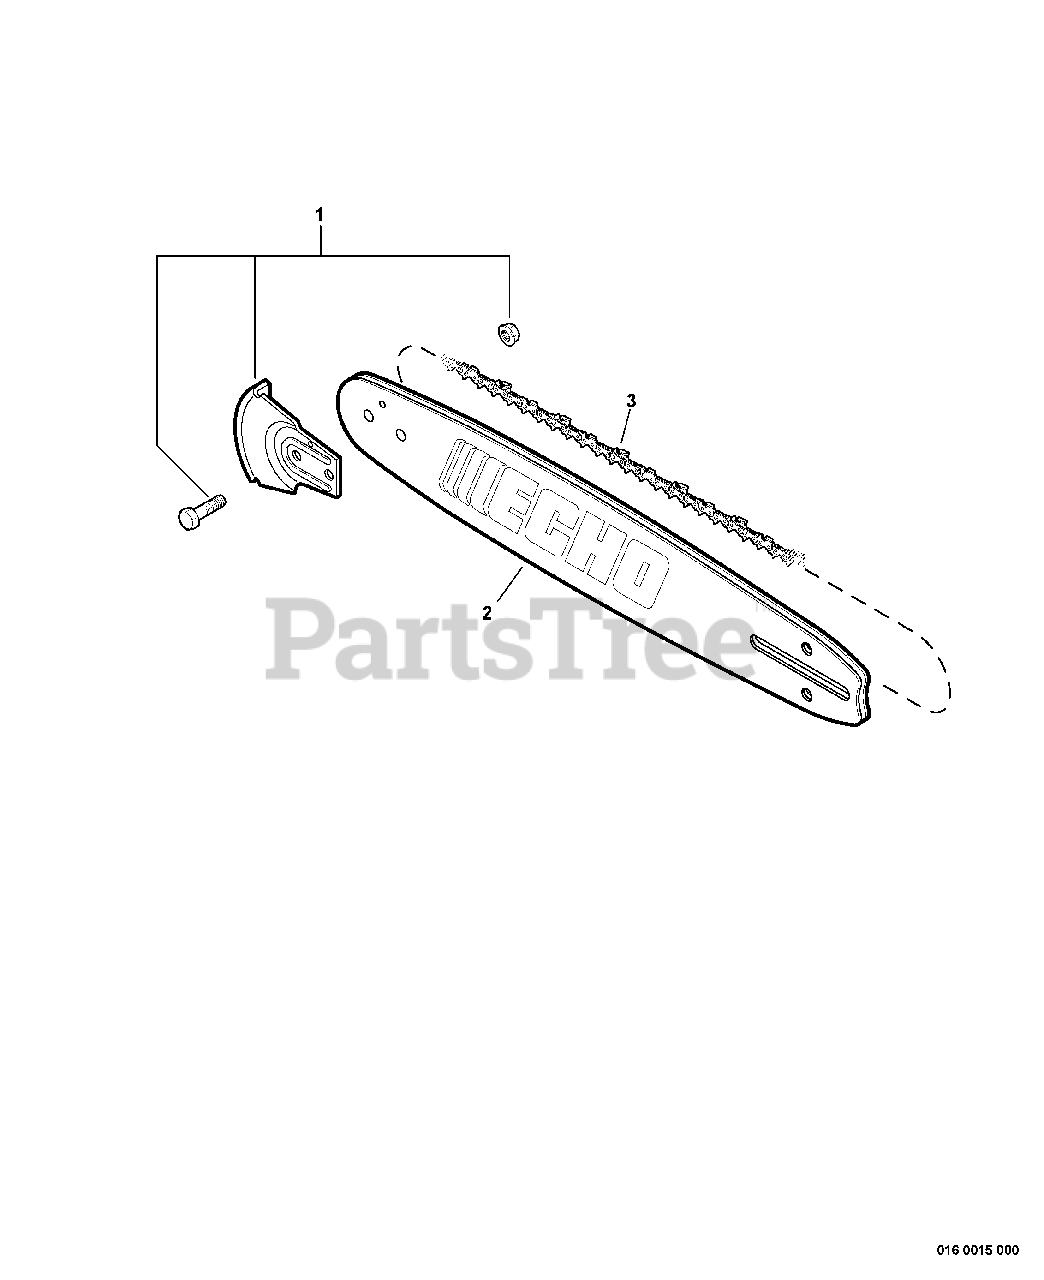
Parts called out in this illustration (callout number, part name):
1	KICK GUARD KIT
2	GUIDE BAR - 20" (50cm)
3	SAW CHAIN - 20" (50cm)
